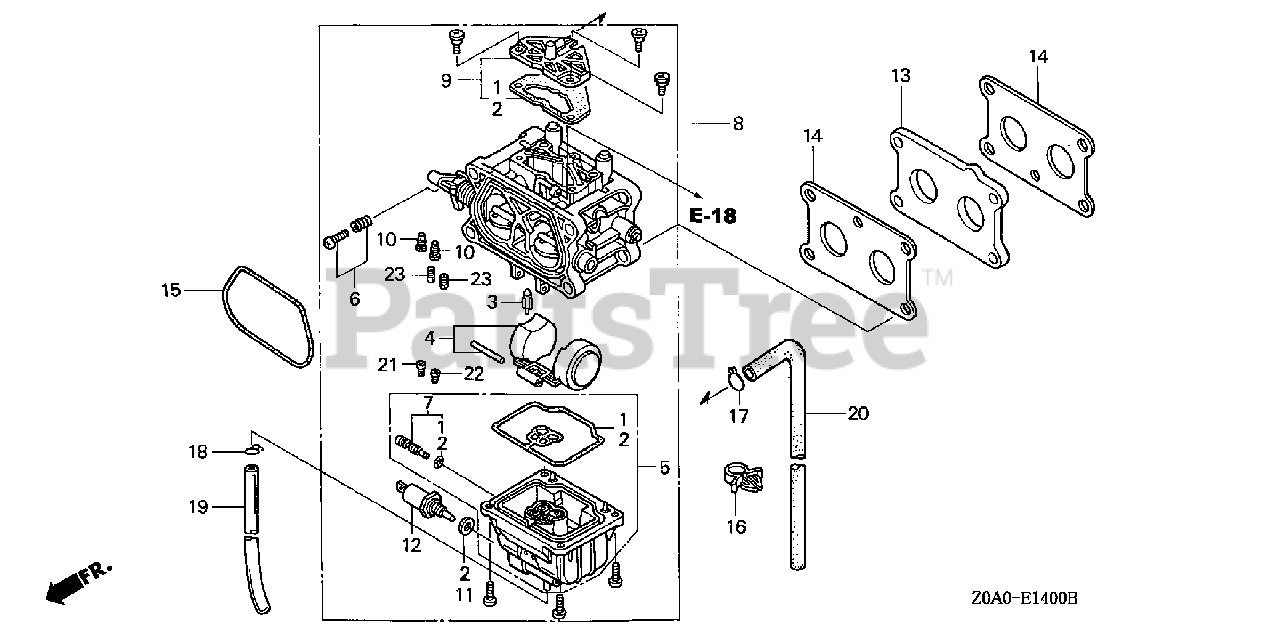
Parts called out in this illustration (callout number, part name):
2	GASKET SET
3	VALVE, FLOAT
4	FLOAT SET
5	CHAMBER SET, FLOAT
6	SCREW SET
7	SCREW SET, DRAIN
8	CARBURETOR ASSY.
9	COVER SET, AIR VENT
10	CAP
11	GASKET
12	VALVE ASSY., SOLENOID
13	INSULATOR, CARBURETOR
14	GASKET, INSULATOR
15	GASKET, AIR CLEANER
16	CLIP, WIRE HARNESS
17	CLIP, TUBE (B8)
18	CLIP, TUBE (B6.5)
19	BULK HOSE, VINYL (4X7X8000) (4X7X300)
20	BULK HOSE, VACUUM (4.5X1000) (4.5X400)
21	JET, MAIN (#82.5)
21	JET, MAIN (#85)
21	JET, MAIN (#87.5)
22	JET, MAIN (#85)
22	JET, MAIN (#87.5)
22	JET, MAIN (#90)
23	JET, PILOT (#37.5)
